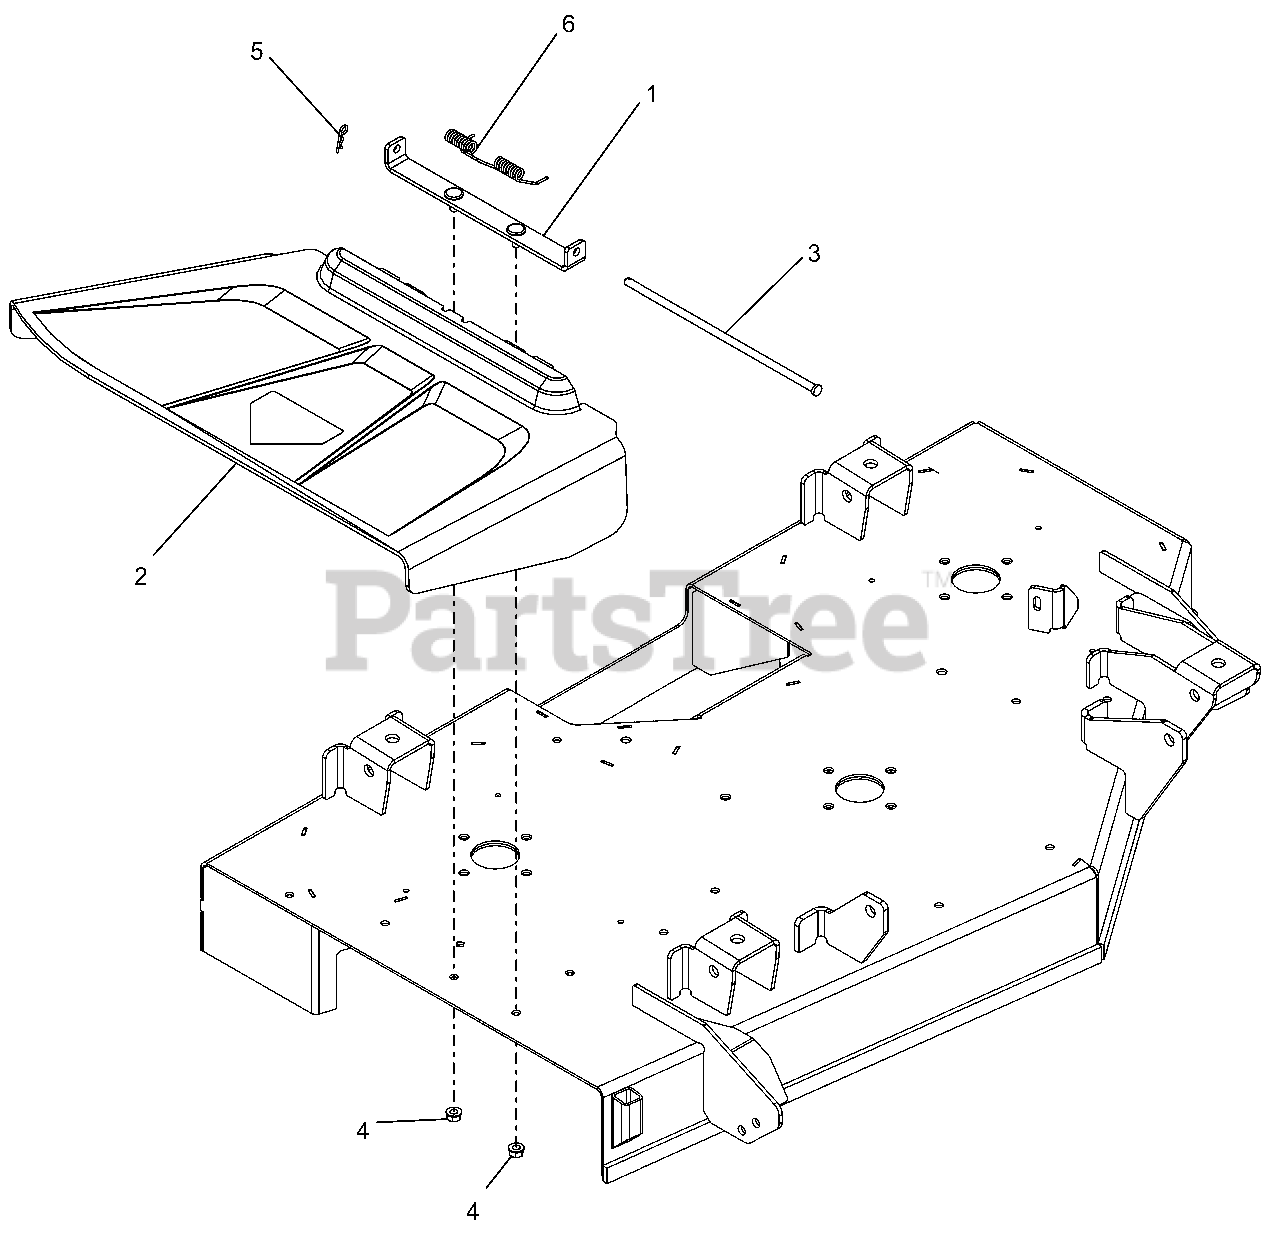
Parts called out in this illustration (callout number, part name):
2	CHUTE, SIDE DISCHARGE
3	PIN, 5/16 X 10.5
4	NUT-LK-TOP-FLG .312-18 GF ZCC
5	PIN, HAIR #213 .08X1.19 ZCC
6	SPRING-TORSION
